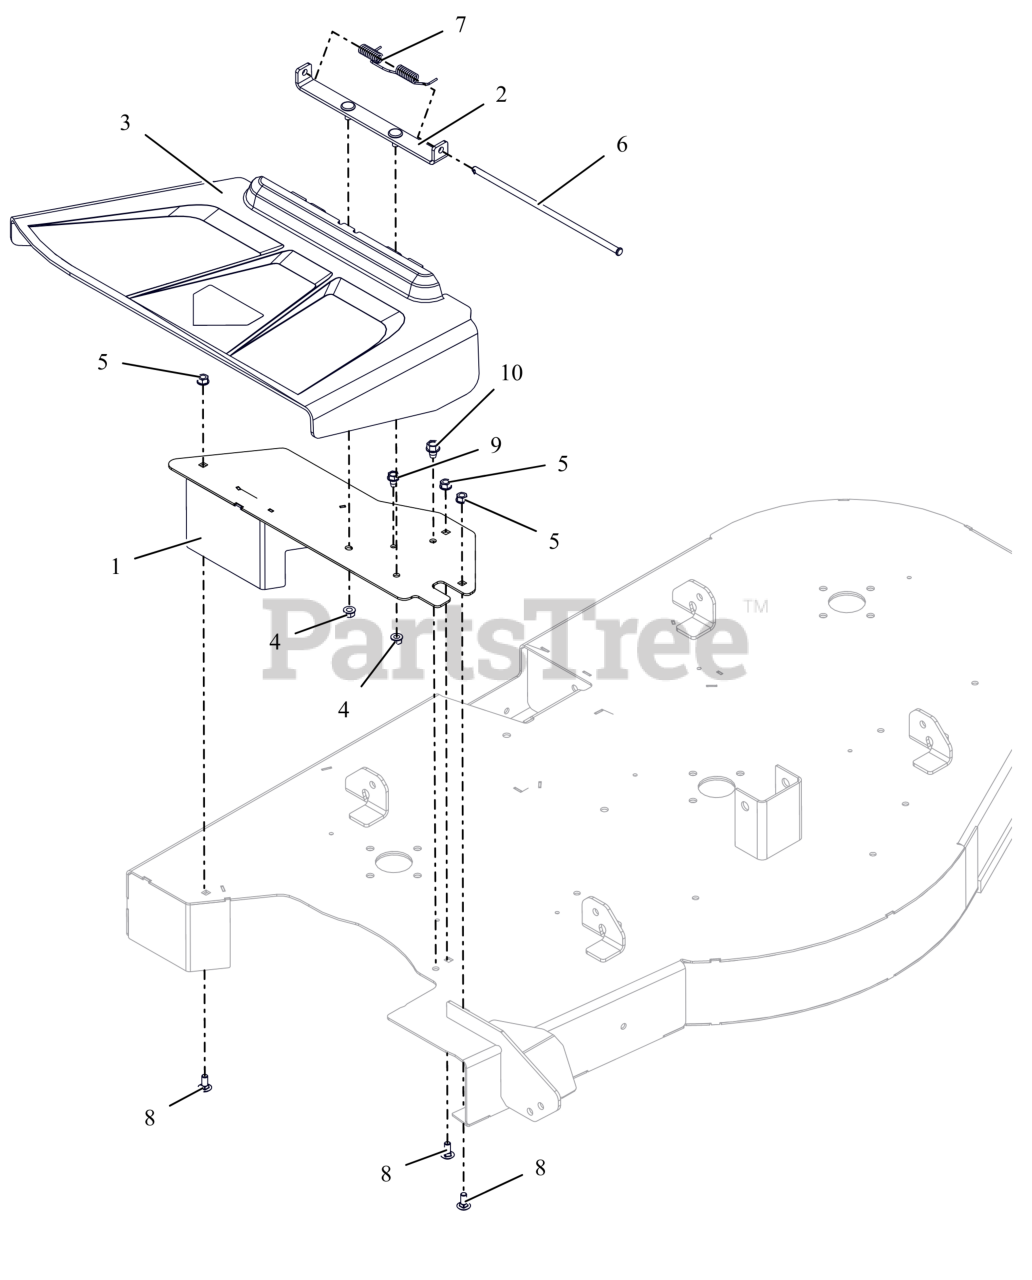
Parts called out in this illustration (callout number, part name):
1	WLDMT, DISCHARGE PLATE (ORANGE)
3	CHUTE, SIDE DISCHARGE
4	NUT,LK-CTR-FLG .31-18 GF ZCC
5	NUT,LK-CTR-FLG .31-18 GF ZCC
6	PIN, SLIC-.312X10.45
7	SPRING-TORSION
8	BLT,RHSN .31-18X.75 G5 ZCC
9	SCR,TAP .312-18X.50 HWH TR ZCC
10	SCR,TAP .375-16X.50 HWH TR ZCC
